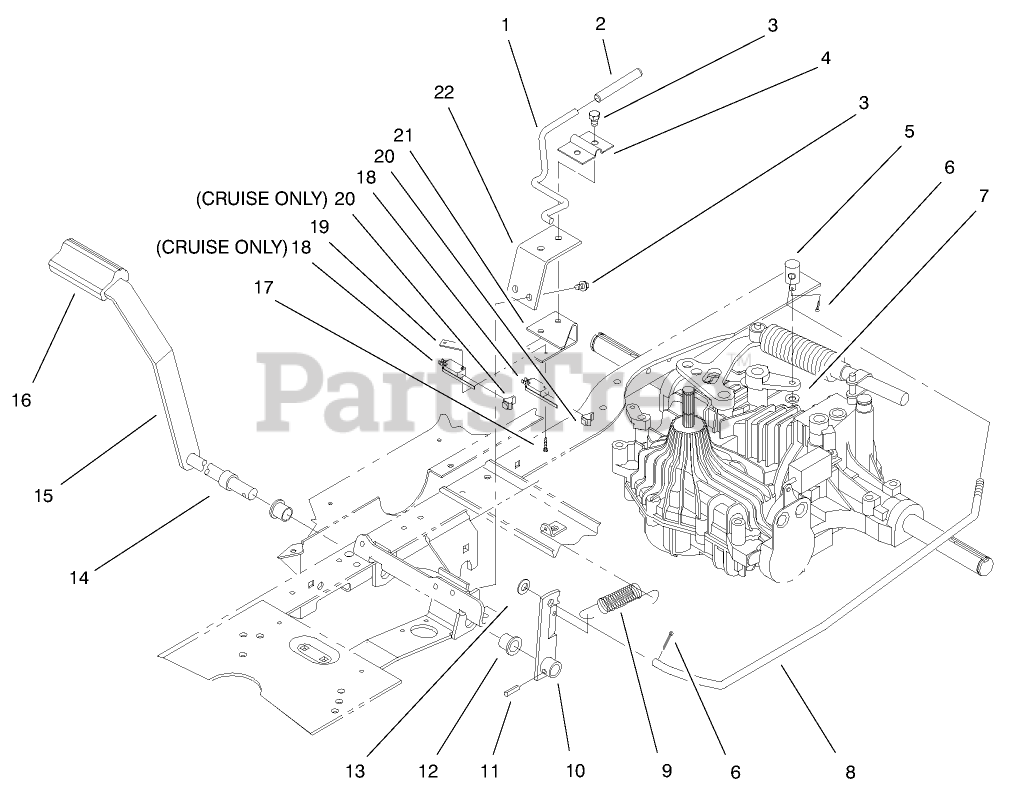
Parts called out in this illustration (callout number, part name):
1	ROD - PARKING BRAKE
2	GRIP - PARKING BRAKE
3	SCREW-HWHTF
4	BRACKET-PARKING BRAKE
5	TRUNNION - BRAKE
6	PIN-COTTER
7	WASHER-PLAIN
10	BRAKE LEVER ASM
11	PIN-SPRING
12	BUSHING-FLANGE
13	WASHER-FLAT
14	SPACER-BRAKE
15	LEVER - BRAKE ASM
16	PAD-PEDAL
17	SCREW-HH
18	SWITCH-MICRO
19	NUT-SPEED
20	PLUNGER-SEAL
21	BRACKET-BRAKE SWITCH
22	SUPPORT-P. BRAKE
